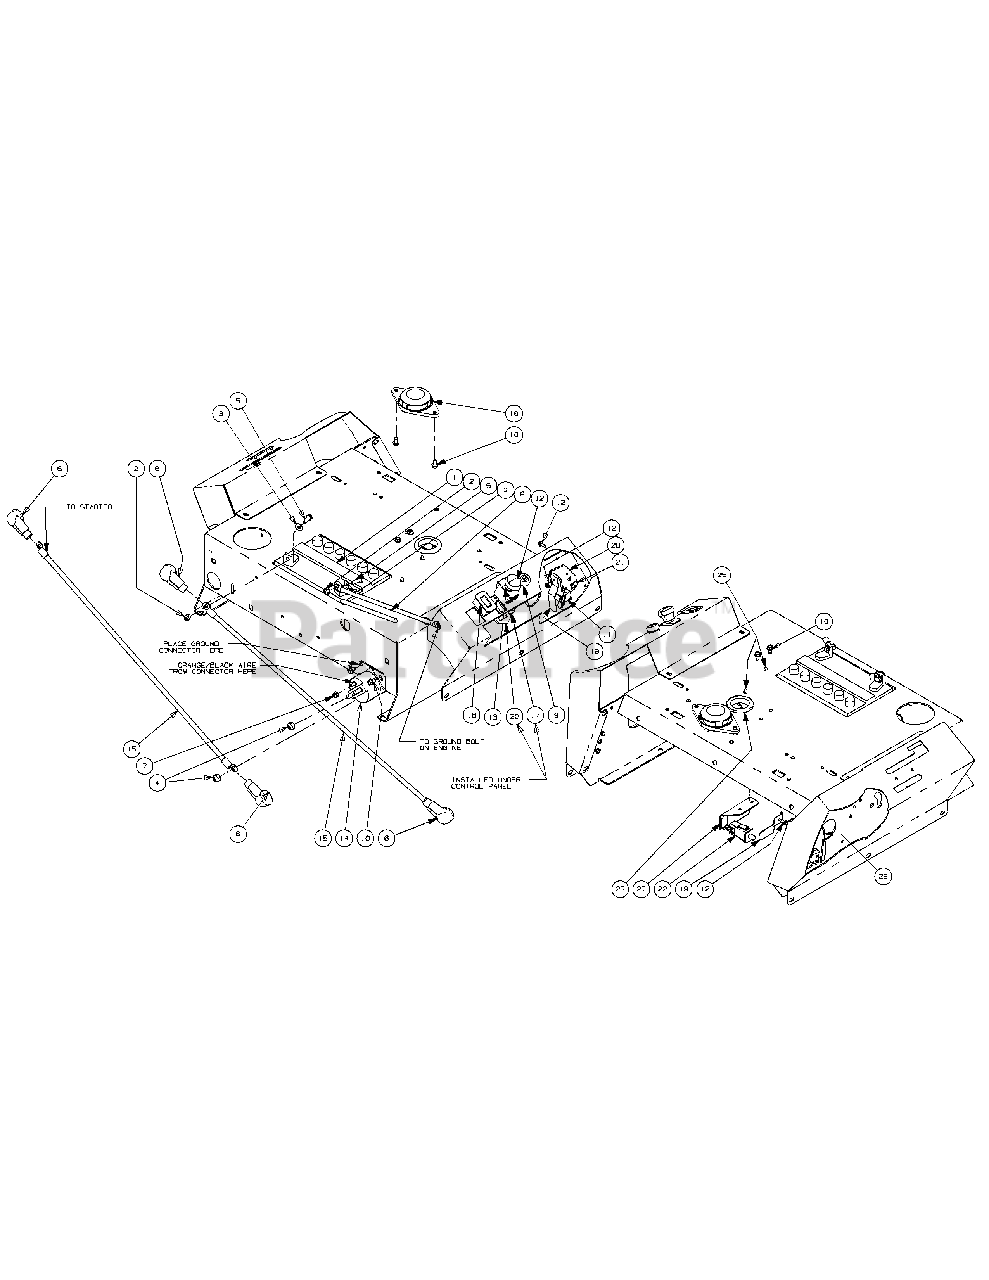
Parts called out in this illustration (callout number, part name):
1	Battery, 12V 225CCA 30Min
2	Lock Nut, Nylon Insert, 1/4-20
3	Flat Washer, 1/4
4	Nylock Nut, 5/16-18
5	Hex Cap Screw, 1/4-20 x .75
6	Boot, 1" OD Rubber Battery-PST Red
7	Lock Nut, Nylon Insert, 10-32
8	Cable, Battery, Black, 17"
9	Nut, 5/8-32, w/Cap
10	Self Tapping Screw, 1/4-20 x 1/2
11	Normally Closed Safety Switch
12	Self Tapping Screw, 10-32 x 1/2
13	Electric PTO Switch
14	Solenoid
15	Cable, Battery, Red, 24"
16	Normally Closed Seat Switch
17	Switch, Ignition, 6 Pin
18	Hour Meter includes:
19	Safety Switch Retainer Spring
20	PTO Switch Bracket
21	U-nut, 10-24
22	Switch, Safety N.O./N.C.
23	Gromment, 1.5 ID x 2.13 OD
25	Electrical Conduit Clip, 3/8
26	Harness Assembly Adaptor
27	Brake Switch Mounting Bracket
28	Bracket, Safety Switch, Right Hand
29	Bracket, Safety Switch, Left Hand
